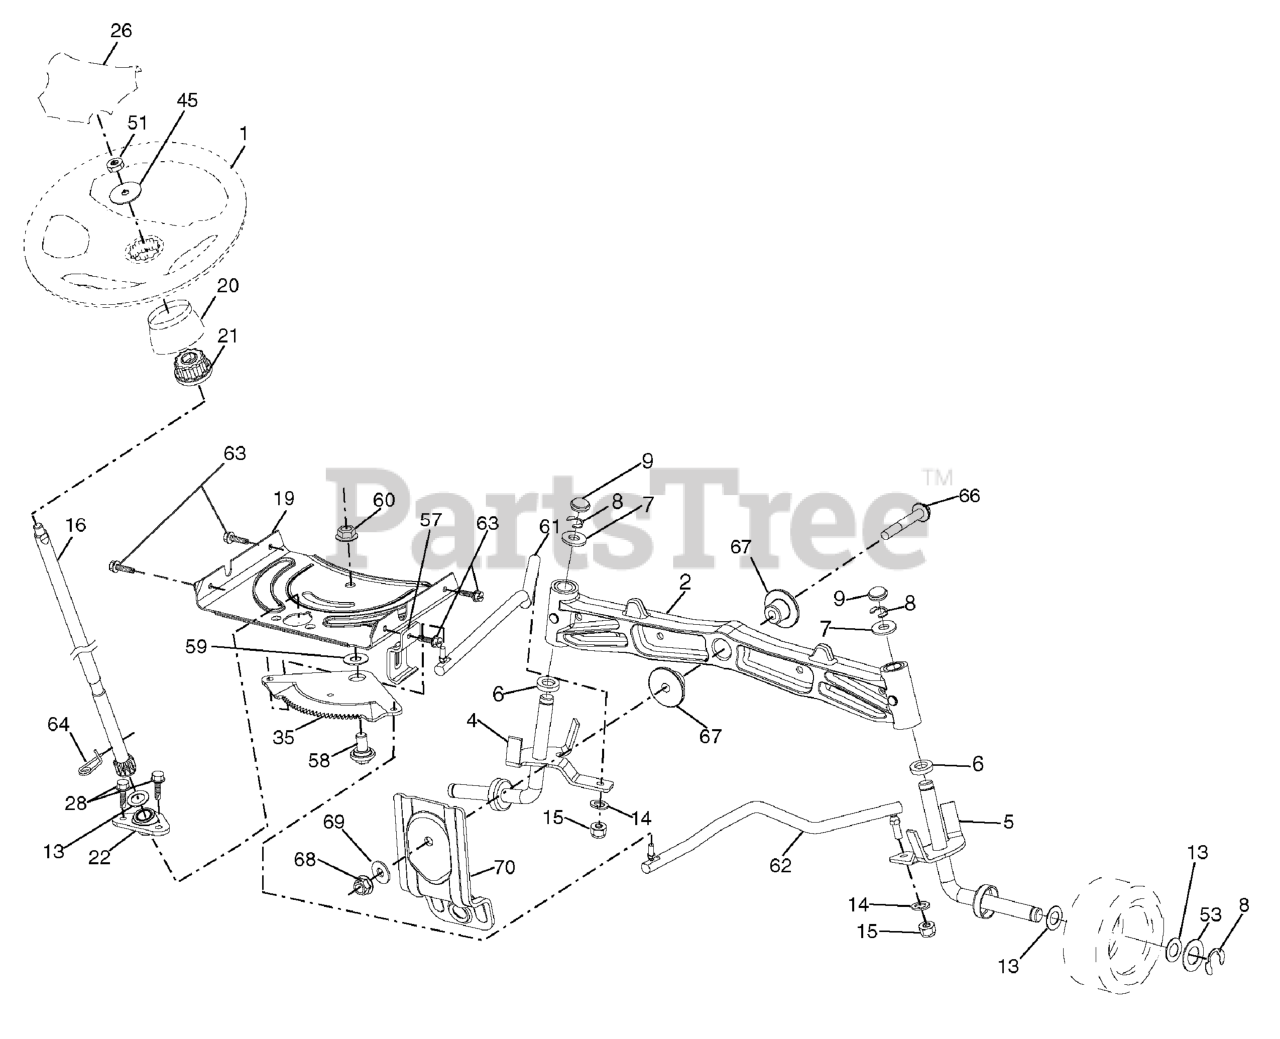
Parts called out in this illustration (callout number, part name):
1	Wheel, Steering
2	Axle Asm., Front
4	Spindle Asm., LH
5	Spindle Asm., RH
6	Bearing, Race Thrust Harden
7	Washer 25/32 x 1-5/8 x 16 Ga.
8	Ring, Clip #T5304-75
9	Cap, Spindle
13	Washer 25/32 x 1-1/4 x 16 Ga.
14	Washer, Lock Hvy Hlcl Spr 3/8
15	Nut, Crown Lock 3/8-24 unf
16	Shaft Steering
19	Plate Steering
20	** Boot, Steering
21	Adapter, Wheel Steering
22	Strg. Supt. Lower
26	Insert, Wheel Steering
28	Screw 3/8-16 x 3/4
35	Gear, Sector Plate
45	Washer 9/16 x 2-3/8 x 12 Ga.
51	Nut Hex Jam Toplock 1/2-20 unf
53	Washer Hardened .793 x 1.637 x .060
57	Bracket Upstop
58	Bolt Shoulder Sector Pivot CFM
59	Washer Thrust Sector Steering
60	Nut Flange Lock 5/8-11
61	Draglink, LH
62	Draglink, RH
63	Screw 5/16-18 x 3/4
64	Retainer Clip Spring Steering
66	Bolt Hex Fghd 7/16-14 x 3 Serr
67	Bushing PM Front Axle
68	Nut Lock Flange 7/16-14 Gr. 5
69	Washer 1.5 x .505 x .118
70	Bracket Deck Susp. Front
